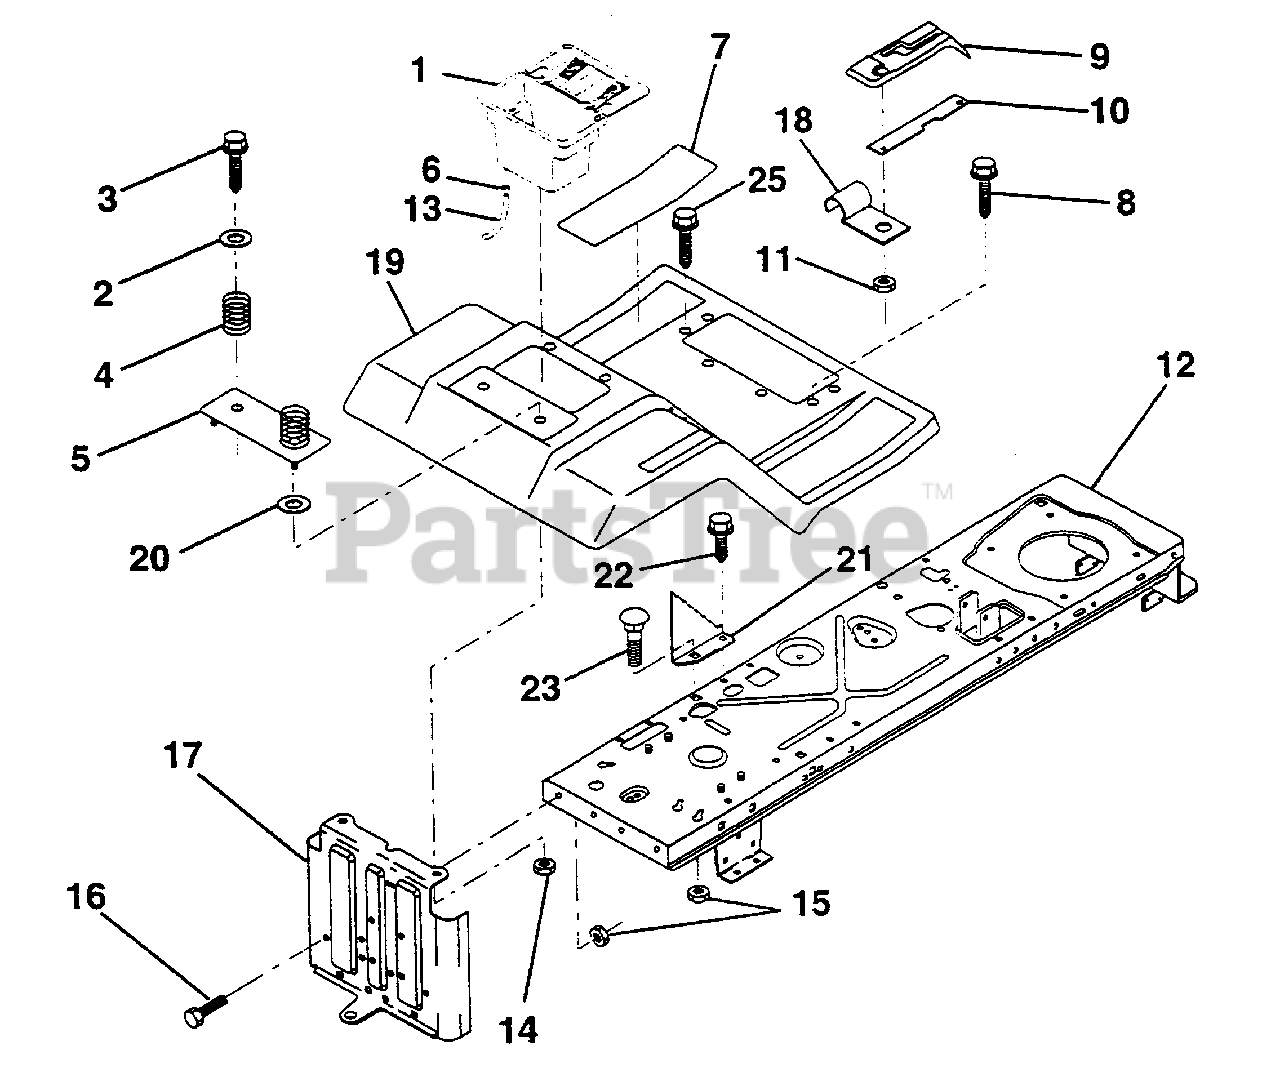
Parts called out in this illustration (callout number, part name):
1	Box, Battery
2	Washer 13/32 x 1-1/4 x 12 Gauge
3	Screw, Hex Washer Head, Thd., Roll. 3/8-16 x 3/4
4	Spring, Compression, Seat
5	Plate Assembly, Battery
7	Pad, Footrest
8	Screw, Hex Washer Head, Thd., Roll. 5/16-18 x 3/4
9	Console, Shift Control
10	Bar, Shift Lock
11	Nut, Self-Threading, Washer Head 3/16
12	Assembly, Chassis
13	Tube, Battery Drain
14	Nut, Hex, Keps 1/4-20
15	Nut, Crownlock 5/16-18
16	Bolt, Hex Head 5/16-18 UNC x 3/4
18	Clip, Insulated
19	Fender/Footrest
20	Washer 9/32 x 7/8 x 13 Gauge
21	Plate, Depth Stop
22	Screw, Thd., Roll. 5/16-18 x 1/2
23	Bolt, Carriage 5/16-18 x 3/4
25	Screw, Hex Washer Head, Thd., Roll. 5/16-18x1
